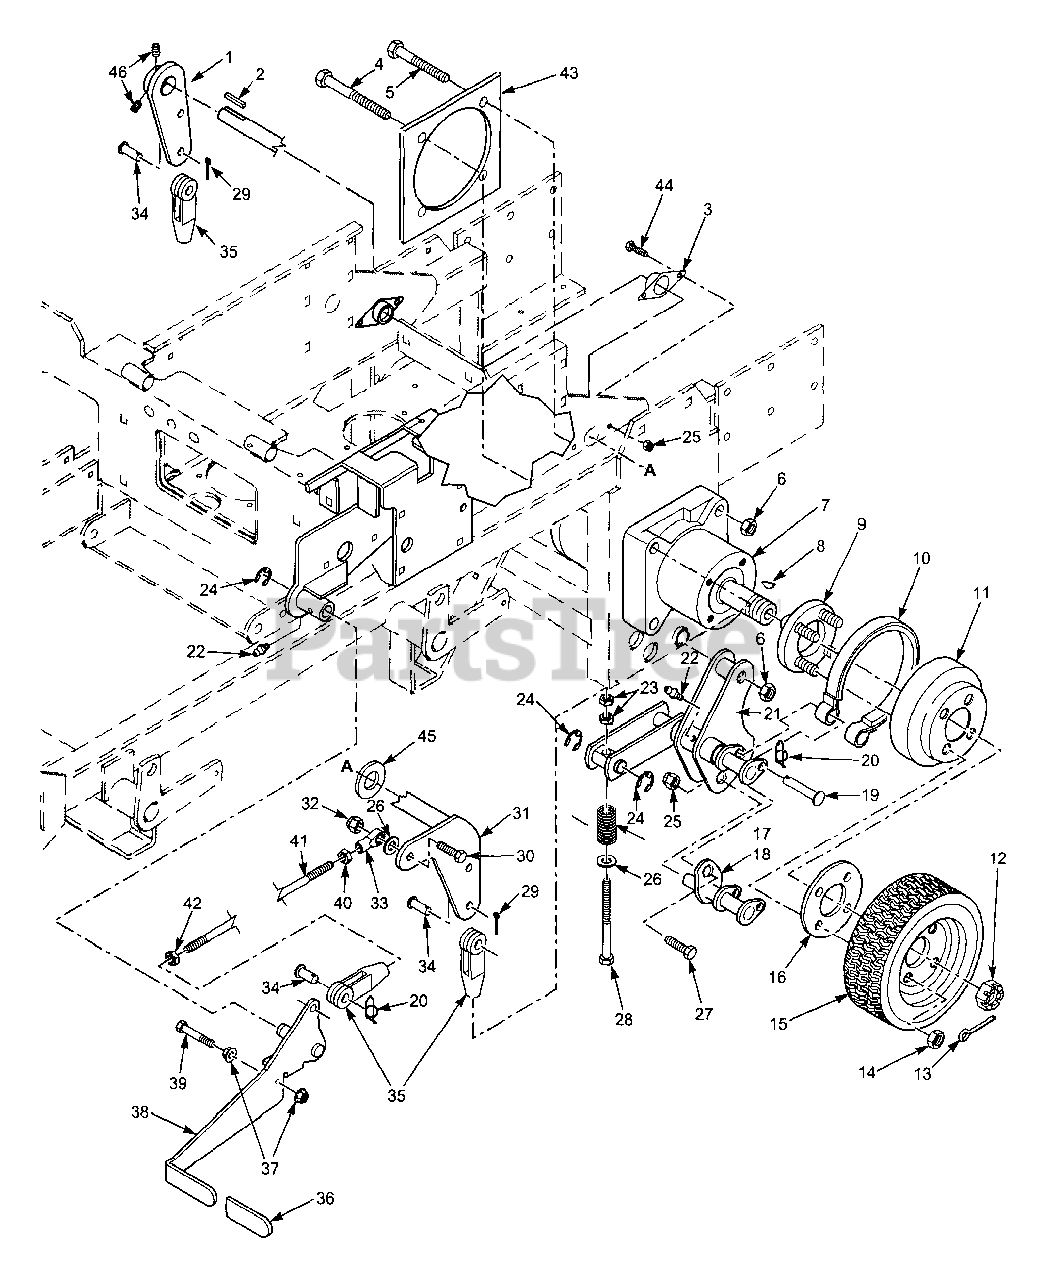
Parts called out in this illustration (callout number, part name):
1	Brake Lever
2	Key, 1/4 x 1/4 x 1"
3	Bushing, Self Align
4	Bolt, Hex Head 1/2-13 x 3-1/2"
5	Bolt, Hex Head 1/2-13 x 2-1/4"
6	Nut, 112-13 Center Lock
7	Wheel Motor Ross
8	Key, Woodruff 5/16 x 1"
9	Wheel Hub Assembly
10	Brake Band Assembly
11	Brake Drum
12	Nut, Hex Castle 1.0-20 UNEF
13	Cotter Pin, 9/64 x 1-1/2"
14	Lug Nut
15	Wheel Assembly (40"), 23 x 8.50-12
16	Wheel Spacer
17	Shaft Weldment, RH
18	Shaft Weldment, LH
19	Clevis Pin, 3/8 x 2"
20	Pin, Rue Cotter 3/8 Dia
21	Brake Linkage LH
22	Grease Fitting, 1/4-28 Self Tap
23	Nut, 3/8-24 UNF
24	Retaining Ring, .625 Ext
25	Nut, Elastic Stop 5/16-18
26	Flatwasher, 3/8- .391 x .938 x .105
27	Bolt, Hex Head 5/16-18 x 1"
28	Bolt, Hex Head 3/8-24 x 5-3/4"
29	Cotter Pin, 3/32 x 3/4"
30	Bolt, Hex Head 3/8-16 x 1-1/4"
31	Brake Shaft
32	Hex Lock Nut, 3/8-16
33	Rod End, 3/8-24 LH Thread
34	Clevis Pin, 3/8 x 1.06
35	Clevis, 3/8-24
36	Grip, Brake Lever
37	Nut, Serr Flange 3/8-16
38	Brake Lever
39	Bolt, Hex Head 3/8-16 x 2-3/4"
40	Nut, 3/8-24 UNF-2B LH Thread
41	Brake Rod
42	Nut, 3/8-24 UNF
43	Plate Weldment, Motor Backing
44	Bolt, Hex Head 5/16-18 x 3/4"
45	Flatwasher, 1.0-1.062 x 1.75 x .10
46	Setscrew, 5/16-18 x 1/4"
